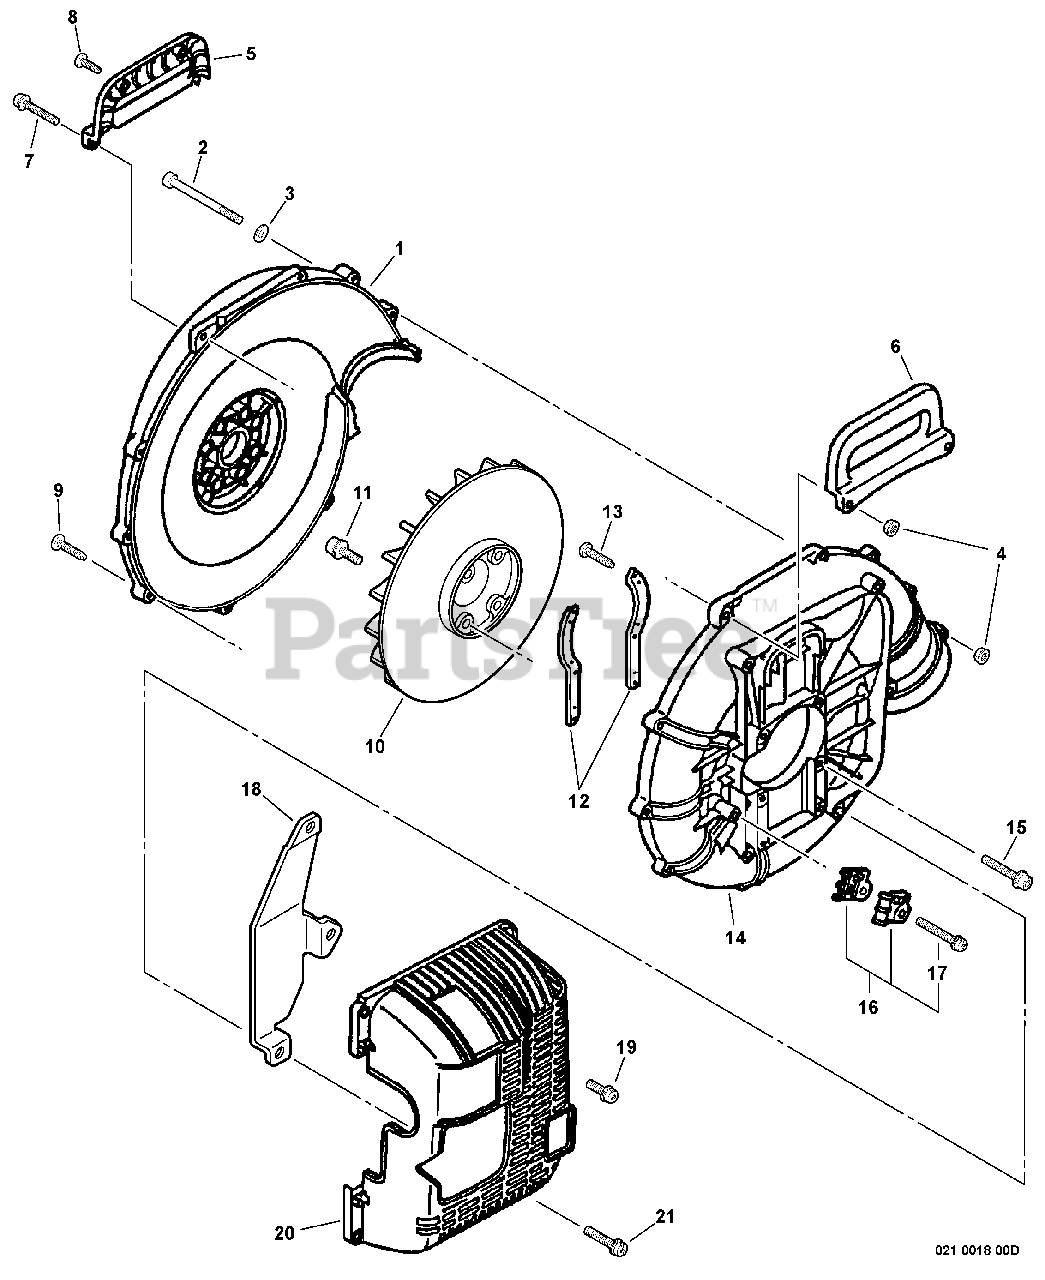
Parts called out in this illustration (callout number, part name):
1	COVER, FAN - INNER
2	SCREW - 5X60
3	WASHER - 5
4	NUT - 5 -- FLANGE
5	HANDLE - INNER -- GRAY
6	HANDLE - OUTER -- GRAY
7	SCREW - 5X45
8	SCREW - 5X16 -- TAPPING
9	SCREW - 5X30
11	SCREW - 5X20
12	BRACKET, ENGINE
13	SCREW - 3X12 -- TAPPING
14	COVER, FAN - OUTER
15	SCREW - 5X32
16	CABLE HOLDER KIT
17	SCREW - 5X25
18	INSULATOR
19	SCREW - 5X10
20	COVER, ENGINE
21	SCREW - 5X18
